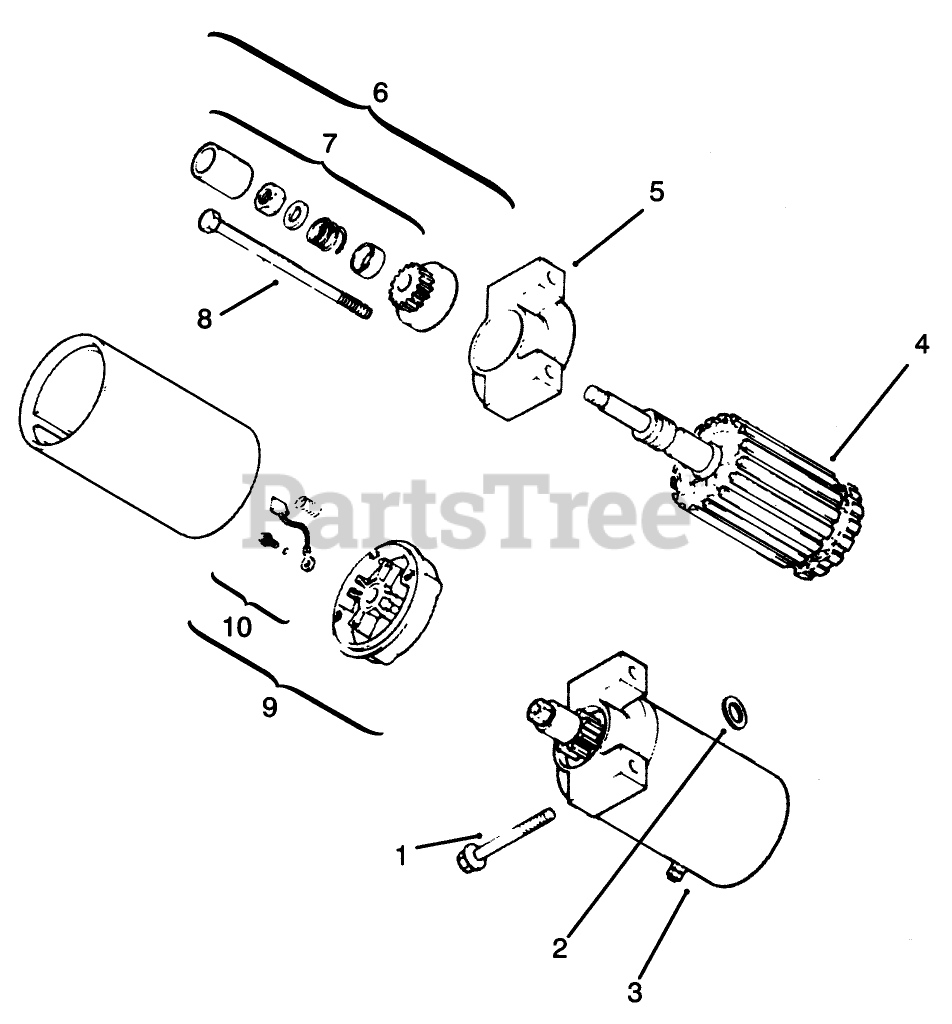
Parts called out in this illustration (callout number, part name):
1	Screw M8x1.25x70 (Only On: 72042, 72063, 72062, 72043)
2	Washer (Only On: 72042, 72063, 72062, 72043)
3	Starter ASM INC 4-10 (Only On: 72042, 72063, 72062, 72043)
4	Armature (Only On: 72042, 72063, 72062, 72043)
5	Cap-Drive End (Only On: 72042, 72063, 72062, 72043)
6	Kit-Drive INC 7 (Only On: 72042, 72063, 72062, 72043)
7	Kit-Drive Parts (Only On: 72042, 72063, 72062, 72043)
8	Screw-HF (Only On: 72042, 72063, 72062, 72043)
9	Cap-Commutator INC 10 (Only On: 72042, 72063, 72062, 72043)
10	Kit-Brush And Spring (Only On: 72042, 72063, 72062, 72043)
